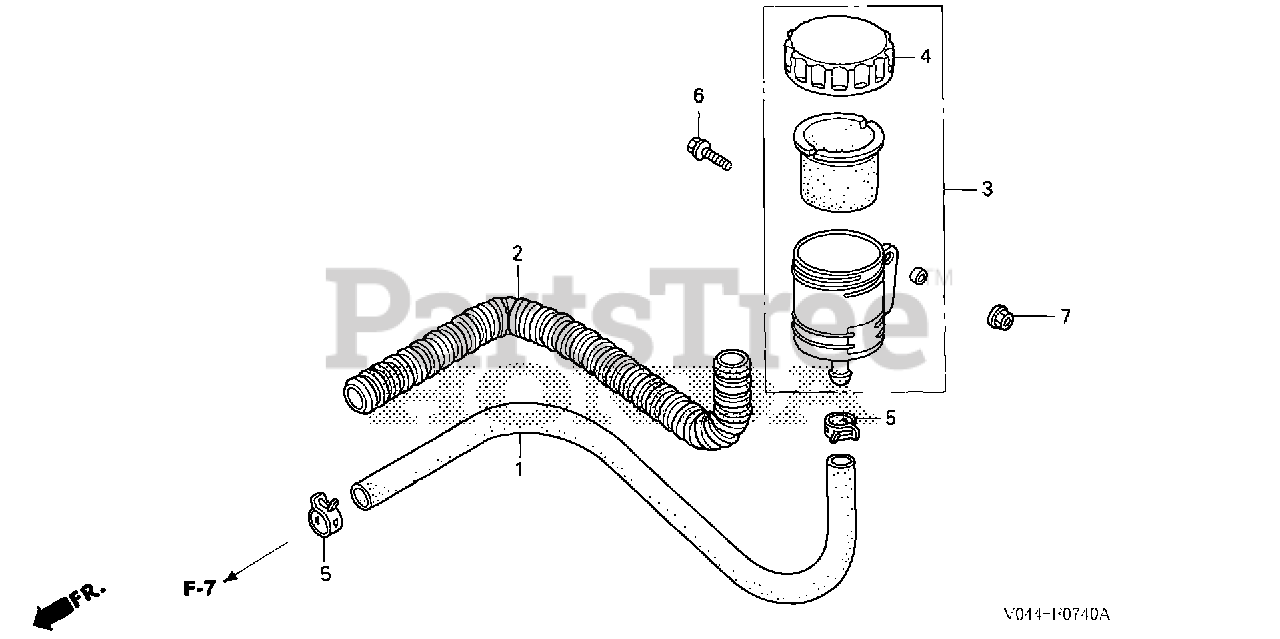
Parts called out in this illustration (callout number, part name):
2	PROTECTOR, OIL TUBE
3	TANK ASSY., OIL
4	FRAME, OIL CAP
5	CLAMP D (19MM)
6	BOLT, FLANGE (6X16) Use from Engine SN 2056820.
7	NUT, FLANGE (6MM)
